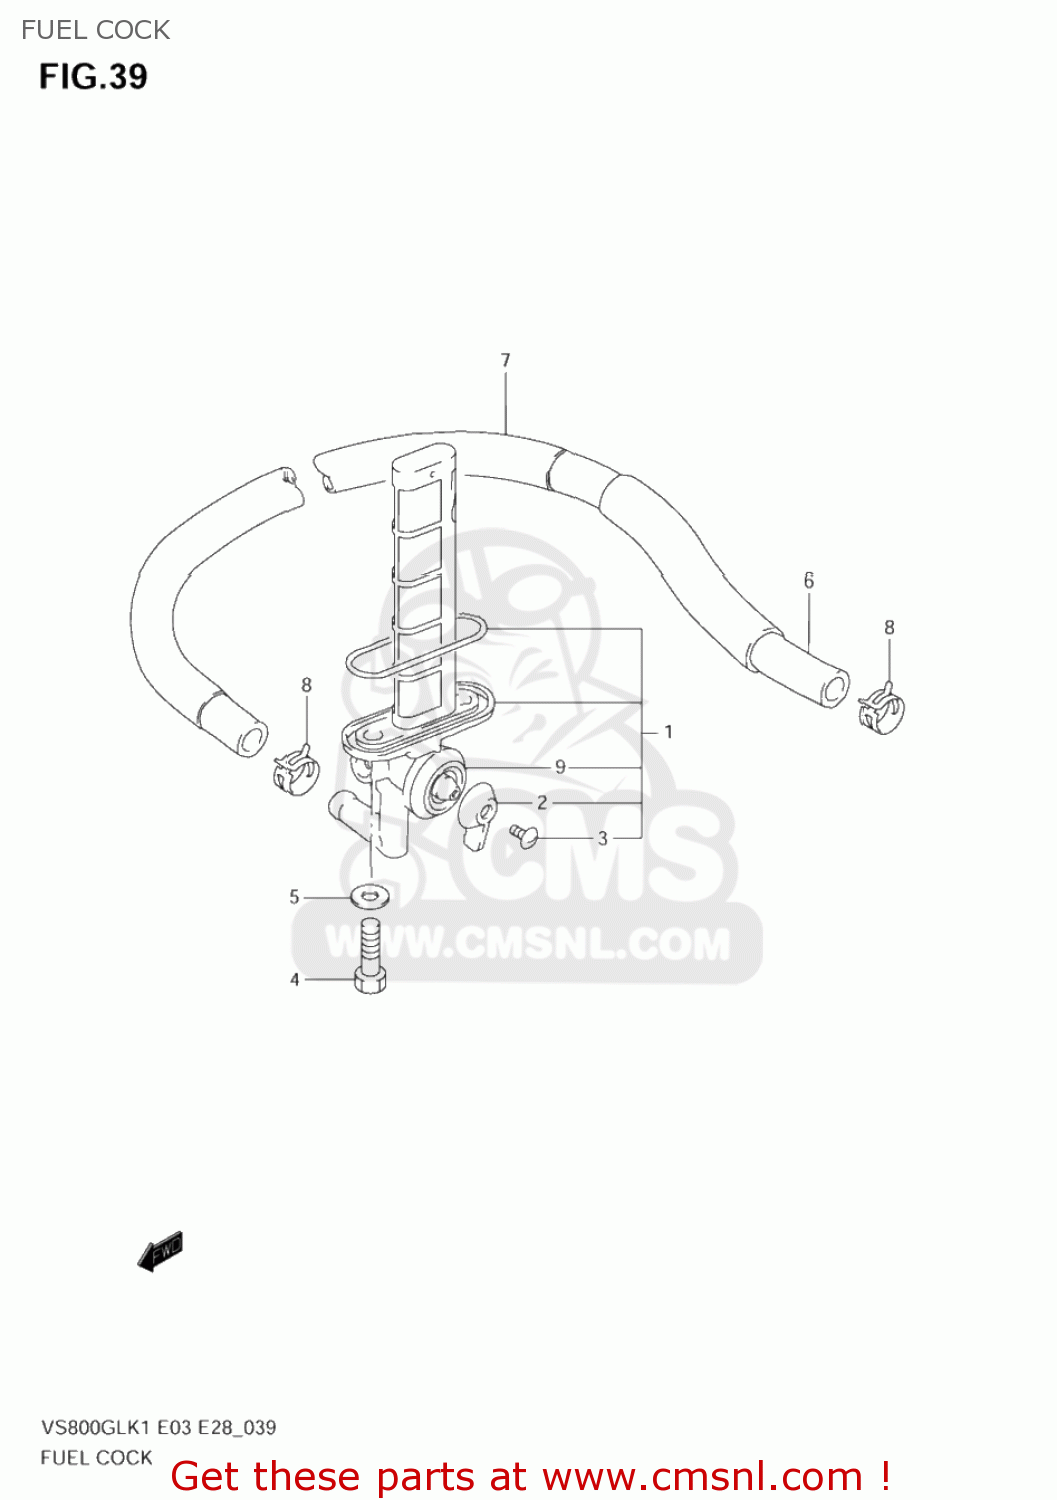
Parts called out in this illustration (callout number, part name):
1	COCK ASSY,FUEL
2	LEVER,FUEL COCK
3	SCREW,COCK LEVER
4	BOLT(6X20)
5	GASKET(6.4X11.5X0.8) (NAS)
6	HOSE,FUEL PUMP & COCK
7	TUBE,FUEL HOSE
8	CLIP
9	O RING,LEVER
